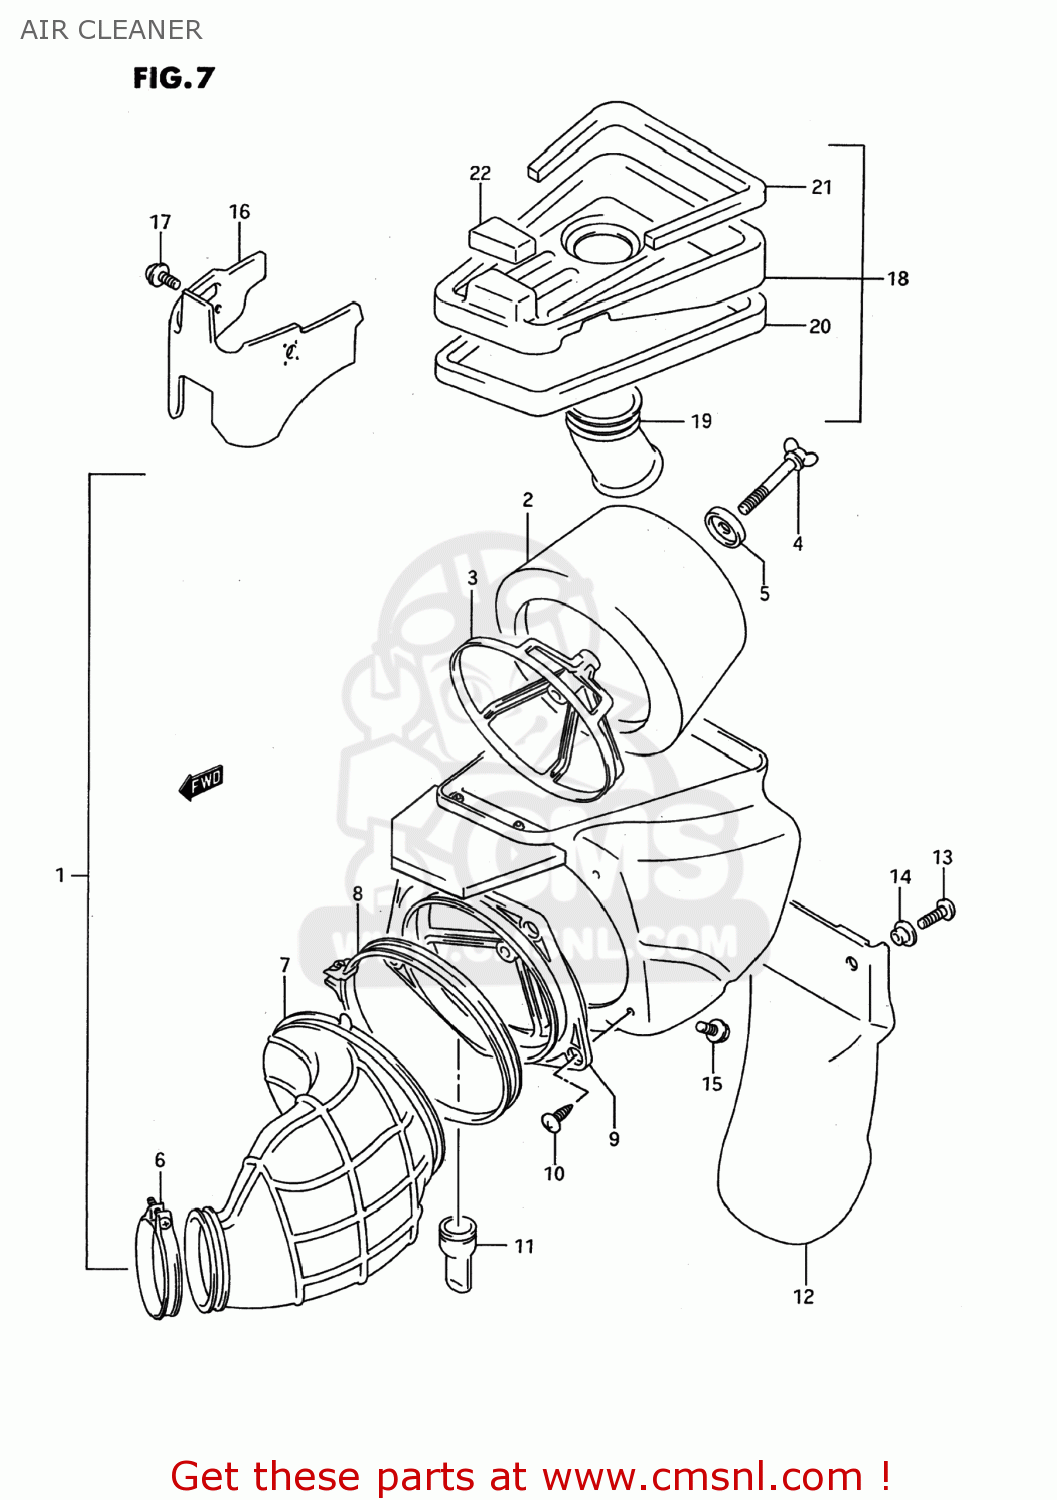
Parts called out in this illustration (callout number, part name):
1	CLEANER ASSEMBLY,AIR
2	FILTER
3	HOLDER,FILTER
4	BOLT,WING
5	WASHER,AIR CLEANER
6	CLAMP
7	TUBE,OUTLET
8	CLAMP
9	BASE,FILTER
10	SCREW
11	CAP,DRAIN
12	GUARD,MUD
13	SCREW
14	COLLAR
15	BOLT
16	GUARD,MUD
17	SCREW(6X12)
18	CAP,AIR CLEANER
19	TUBE,INLET
20	GASKET,CAP (NAS)
21	CUSHION
22	CUSHION
